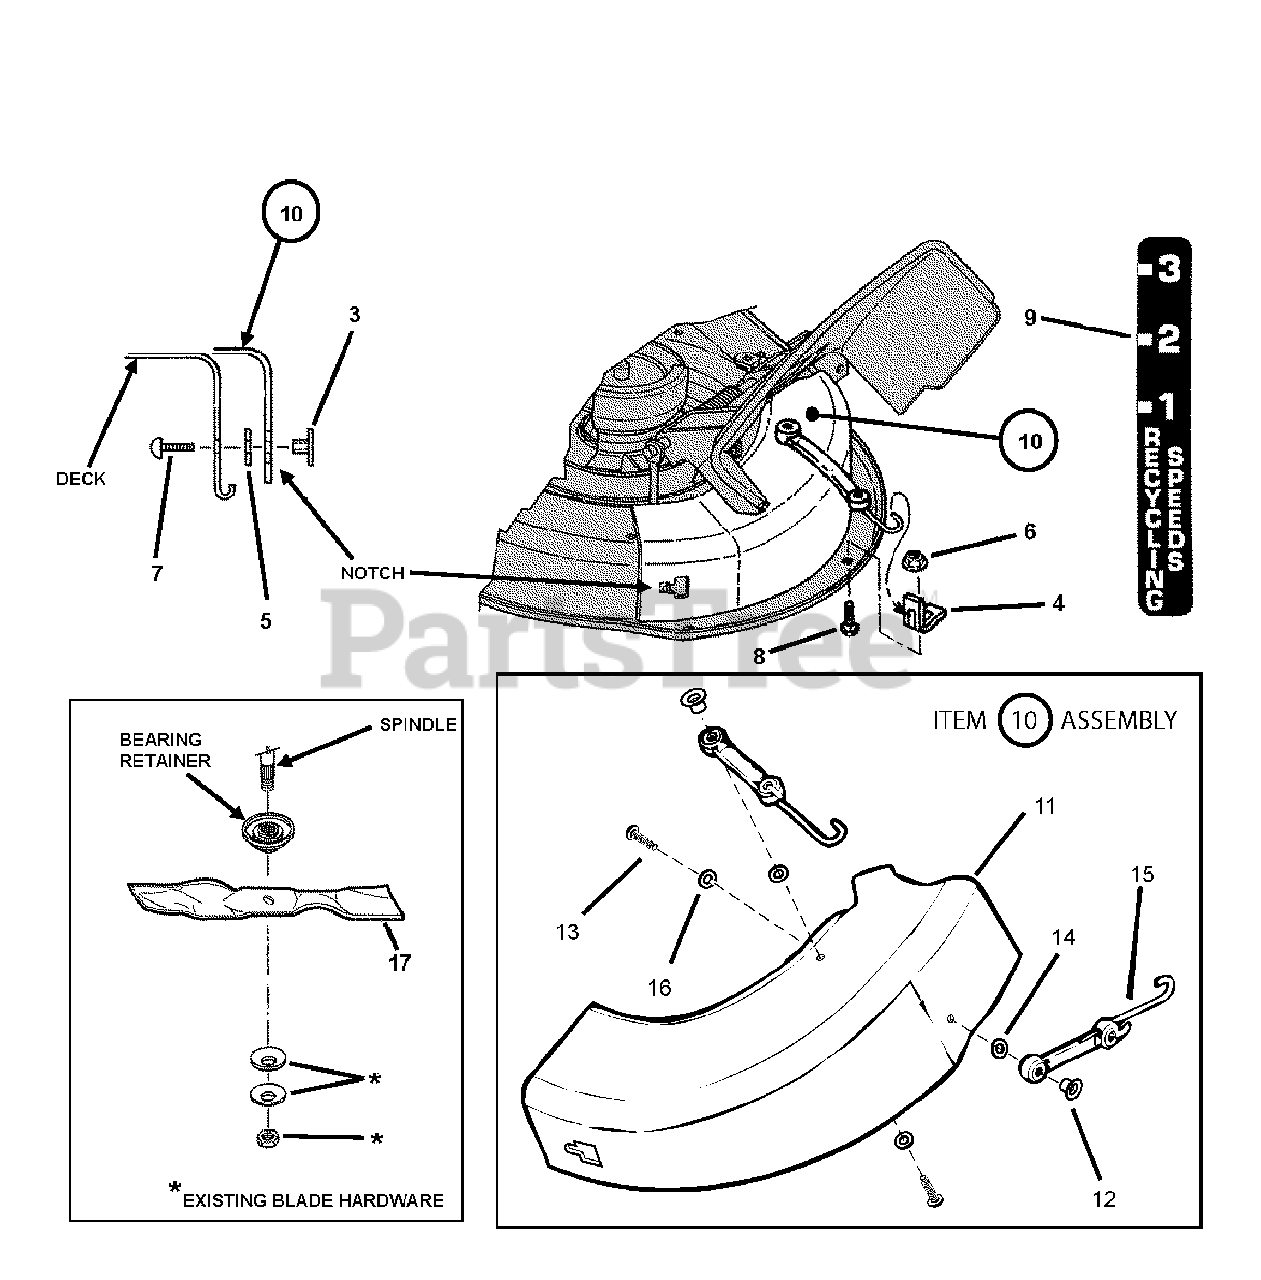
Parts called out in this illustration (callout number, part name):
2	WASHER, Blade
3	NUT, Tee 5/16
4	BRACKET, Strap Mounting
5	WASHER, Flat
6	NUT, Hex Flange Lock, 3/8 - 16
7	SCREW, 5/16 - 18 x 5/8
8	BOLT, Carriage, 3/8 - 16
9	DECAL, Recycling Speeds
10	MULCHING COVER ASSEMBLY
11	MULCHING COVER *
13	SCREW, 5/8 - 10
14	WASHER, Flat
15	STRAP, Mounting Bag Adapter
16	WASHER, Flat
17	BLADE, Wave Mulch, 19-1/2"
